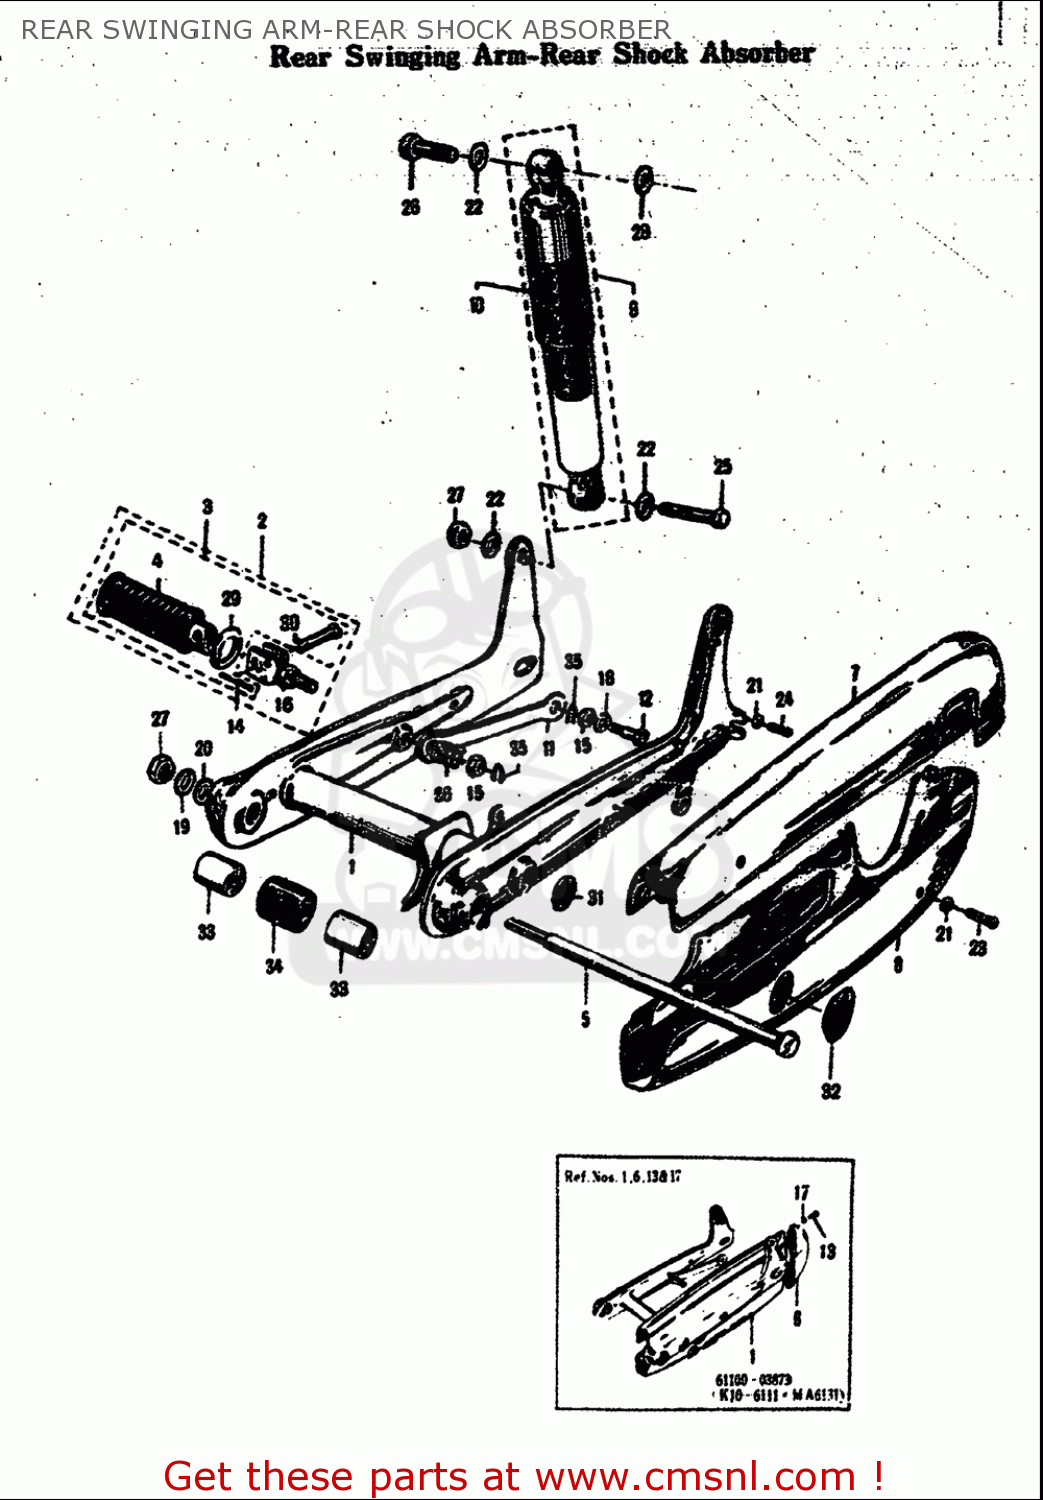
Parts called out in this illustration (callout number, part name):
15	NUT
16	NUT
17	WASHER,LOCK
18	WASHER,LOCK
19	WASHER,LOCK
20	WASHER
21	WASHER
22	WASHER
24	BOLT(6X14)
28	WASHER(10.5X20X3.2)
29	WASHER(19.5X32X2)
30	PIN
31	CAP(OD:26)
32	CAP(OD:40)
34	CUSHION
35	SPRING,RETAINER
